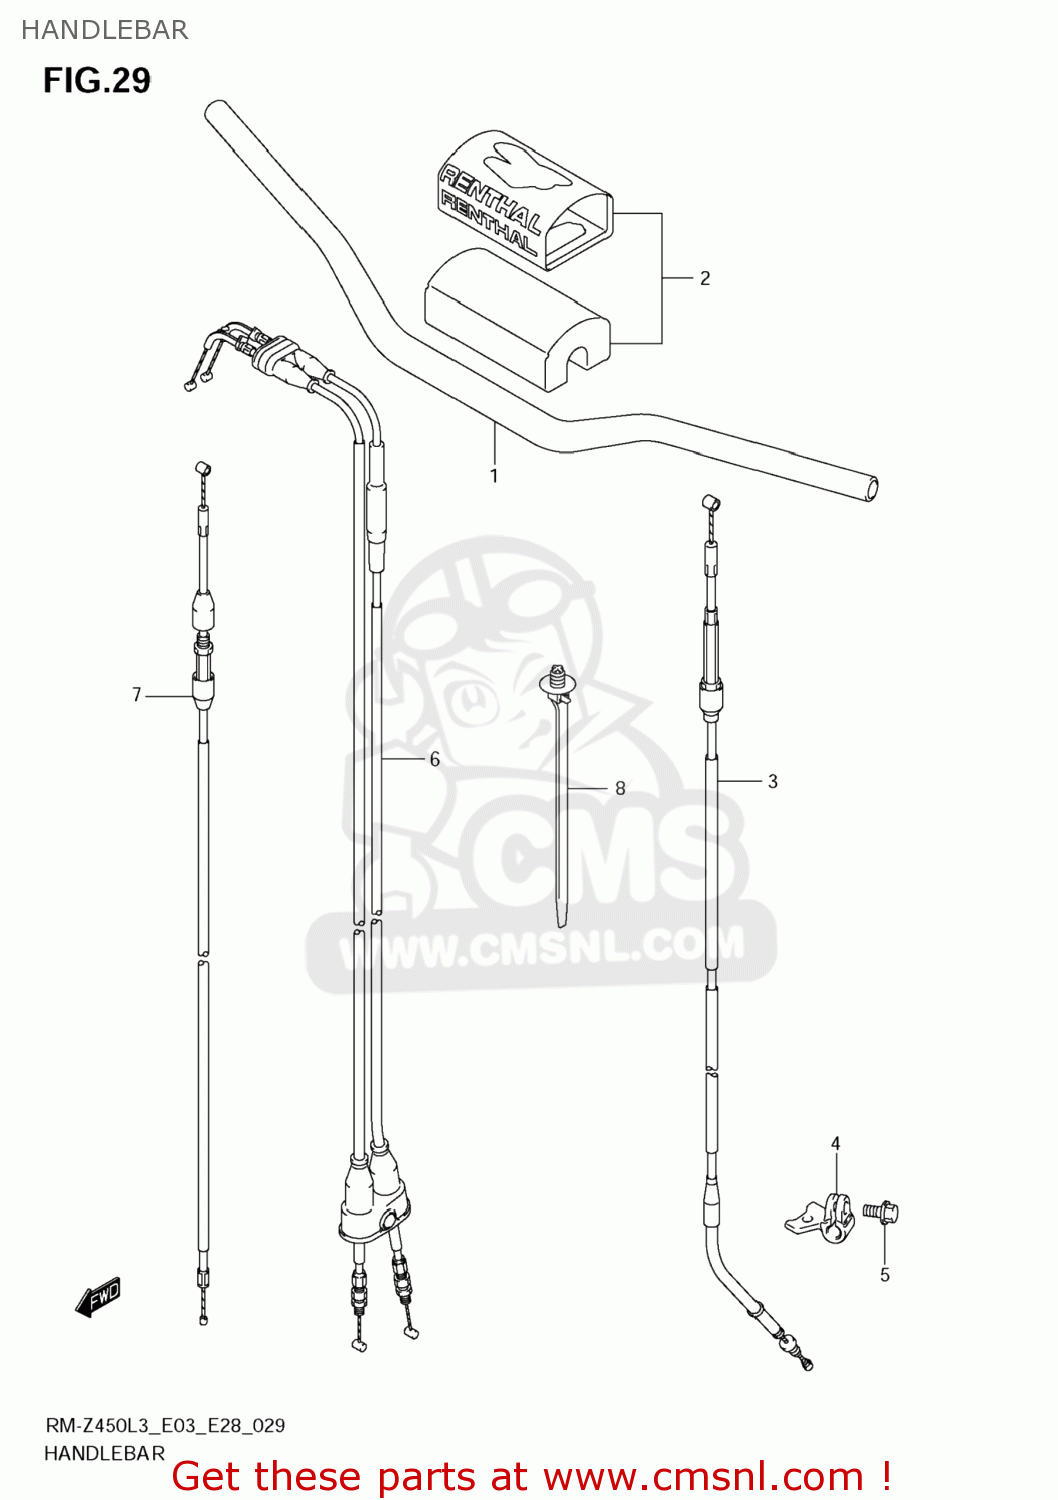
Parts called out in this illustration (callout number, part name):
1	HANDLEBAR
2	PAD SET,HANDLEBAR (NAS)
3	CABLE ASSY,CLUTCH
4	BRACKET,CLUTCH CABLE
5	BOLT
6	CABLE SET,THROTTLE
7	CABLE ASSY,HOT STARTER
8	CLAMP(L:154)
